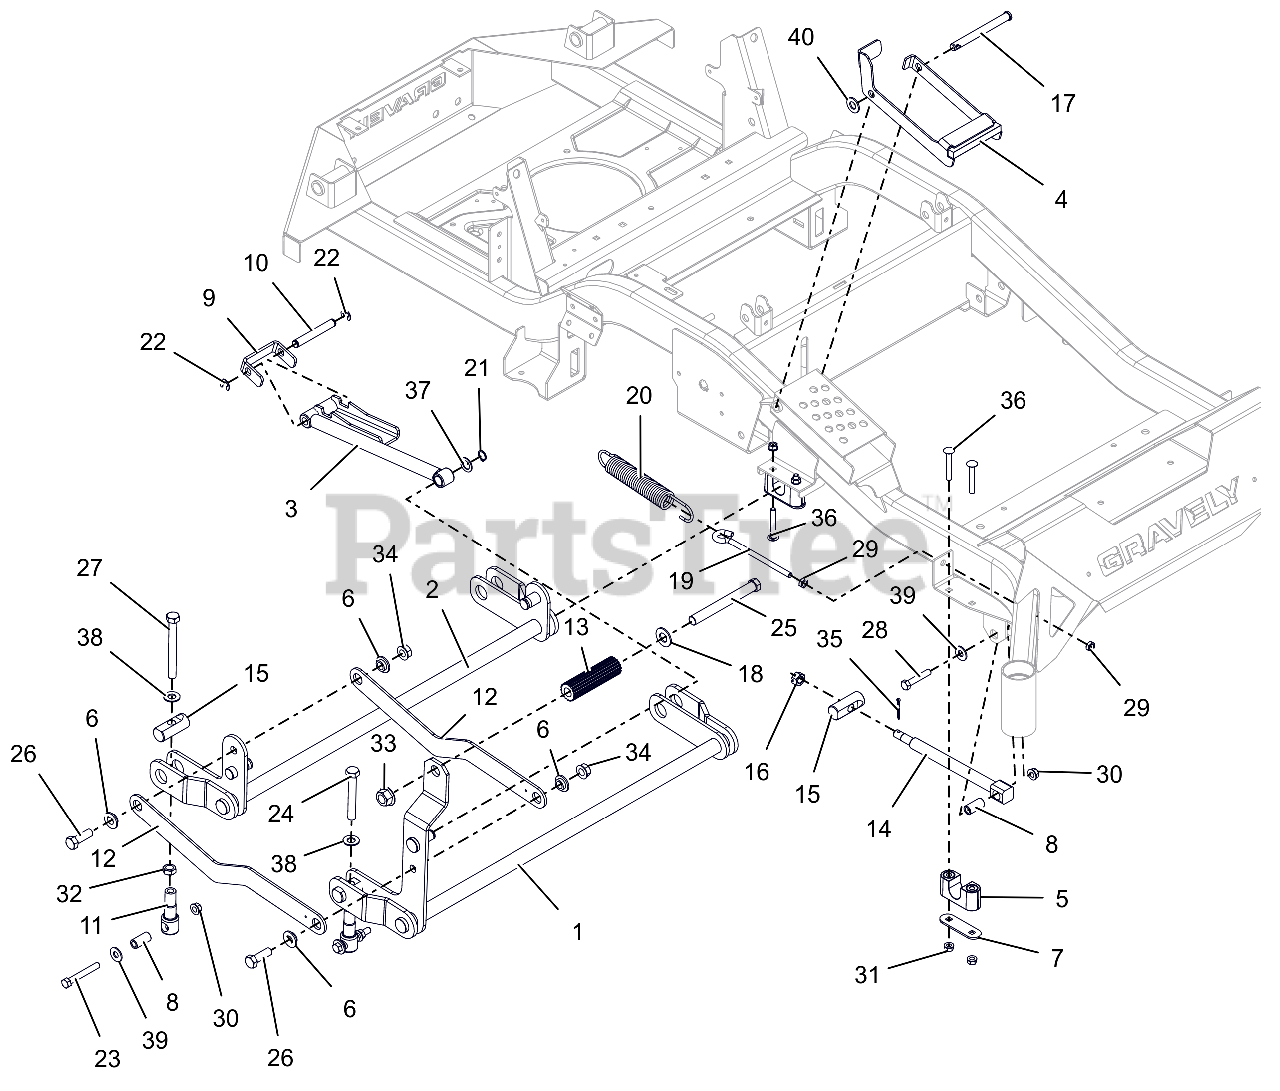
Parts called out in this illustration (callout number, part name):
1	WLDMT, FRONT DECK LIFT PIVOT
2	WLDMT, REAR DECK LIFT PIVOT
3	WLDMT, HOC ARM
4	BRKT, HOC TRANSFER LOCK
5	ASM-BUSHING, DECK LIFT
6	BSHG-FLG .515X.750X.310X1.120
7	PLATE, BEARING SUPPORT
8	SPACER, DECK LEVELING
9	BRKT, HOC LINE
10	ROD, HOC PIVOT
11	LINK, DECK LIFT FORMED
12	LINK, DECK LIFT
13	ROD, FOOT PEDAL (BLACK)
14	DRAG,LINK-HD
15	PIN, DECK LIFT
16	NUT-SL .50-13
17	PIN, SLIC-.500X4.97X4.55 -ZC
18	WSHRFLT 5/8SAE CARBHARD FBP
19	BOLT,.38-16 X 5.25-.62 DIA EYE
20	SG-TENS .162X1.25X8.25 WLD 25
21	RG-RTNG-EXT .625X.050
22	RG-RTNG-EXT .500X.042 (E)
23	BLT, HEX .38-16X2.75 G8 ZCC
24	BLT, HEX 0.5-13X3.5F GR5 ZCC
25	BLT, HEX .62-11X5.50 G5 FBP
26	BLT,HEX .50-13X1.50 G5 ZCC
27	BLT, HEX .50-13X4.50F G8 ZCC
28	BLT,HEX .38-16X2.00 G5 ZCC
29	NUT-JAM .375-16 G2 ZCC
30	NUT-LK-TOP-FLG .38-16 ZC120
31	NUT,LK-CTR-FLG .31-18 GF ZCC
32	NUT-JAM .500-13 G2 ZCC
33	NUT,FLG-TOP LK .625-11 FBP
34	NUT-LK-TOP-FLG .500-13 GF ZCC
35	PIN,CTR.12X1.25EXTPRSQCT ZC120
36	BLT, RHSSN.31-18X2.25 G5 ZCC
37	WSHR, FLT .630X1.005X.062 ZCC
38	WSHR, FLT .557X1.040X.102 ZCC
39	WSHR,FLT .438X1.00X.083 ZCC
40	WSHR,FLT .531X1.062X.095 ZCC
